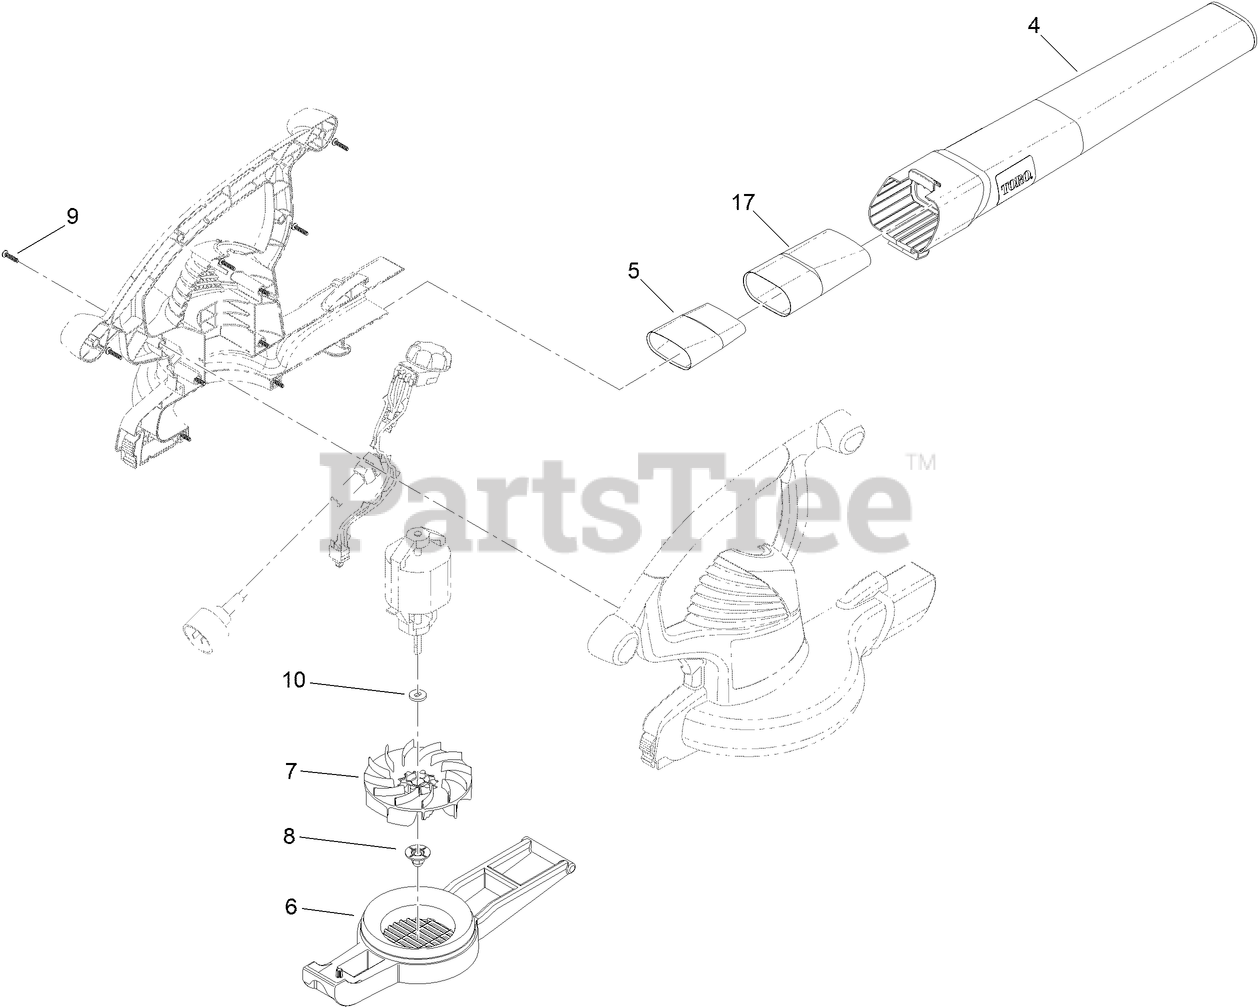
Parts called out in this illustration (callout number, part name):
4	TUBE-BLOWER
5	TUBE-INSERT, SUPER
6	COVER-INLET
7	IMPELLER-PLASTIC
8	NUT-IMPELLER
9	SCREW-PPH
10	WASHER-IMPELLER
17	TUBE-INSERT
